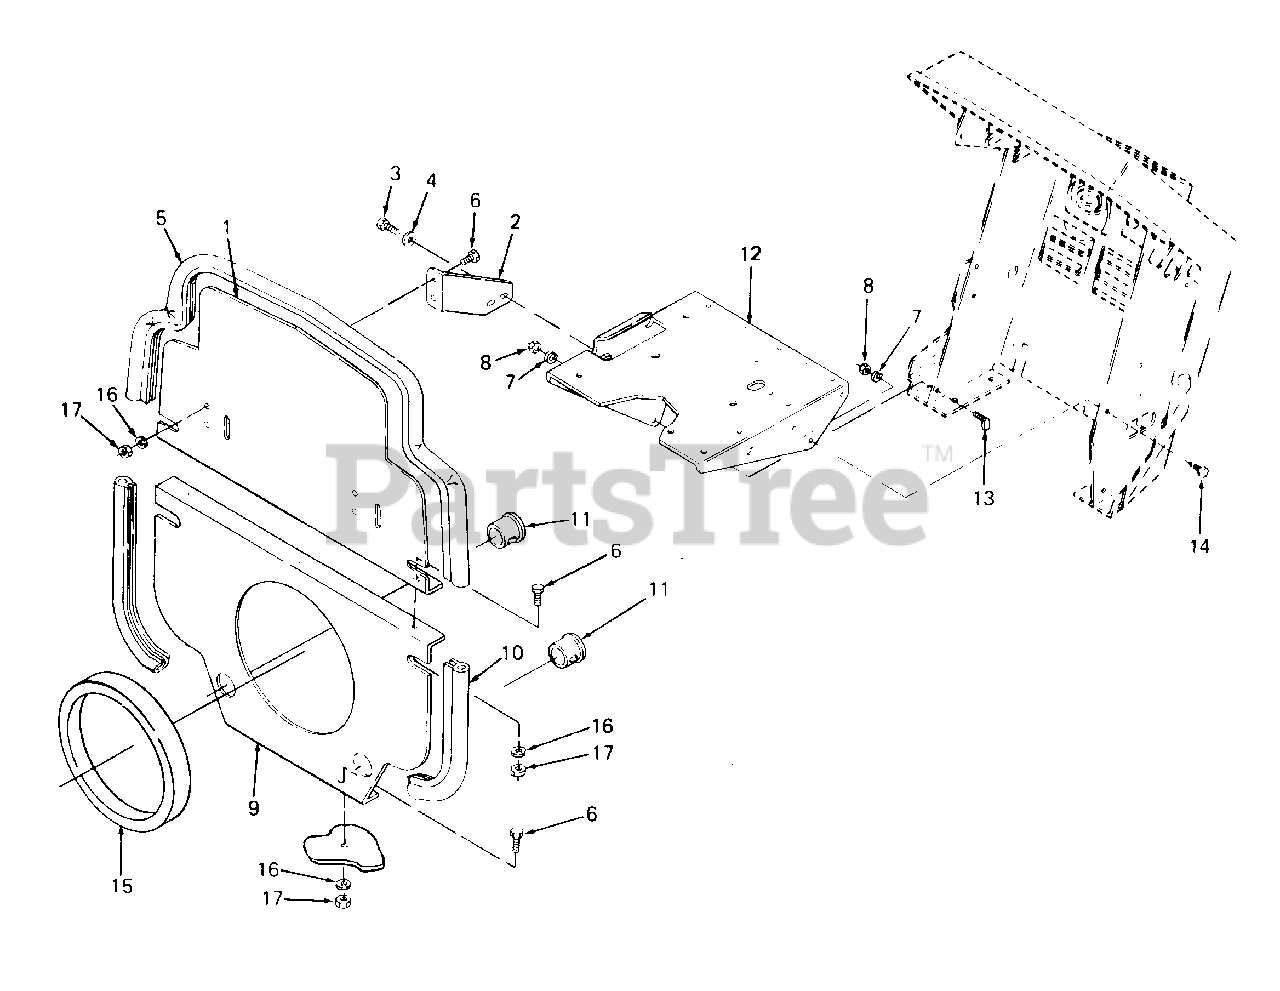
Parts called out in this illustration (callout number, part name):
3	Screw, Hex Cap, 5/16-18 X.50 Lg GR5
4	Washer, Bell, .345 X .88 X .060 Thk
5	Seal, Bulkhead, 36" Lg
6	Screw, Hex Cap, 1/4-20 X.50 Lg GR5..
7	Washer, Lock, 1/4
8	Nut, Hex, 1/4-20 GR5
9	Bulkhead, Lower
10	Seal, Bulkhead, 10" Lg
11	Bushing, Snap, 7/8 ID
12	Tray Assy, Battery
13	Bolt, J-Type, 1/4-20
14	Screw, Hex Cap, 1/4-20 X.62 Lg GR5..
15	Ring, Foam Sealing
16	Washer, Bell, .265 X .75 X .062 Thk
17	Nut, Hex Top Lock, 1/4-20
